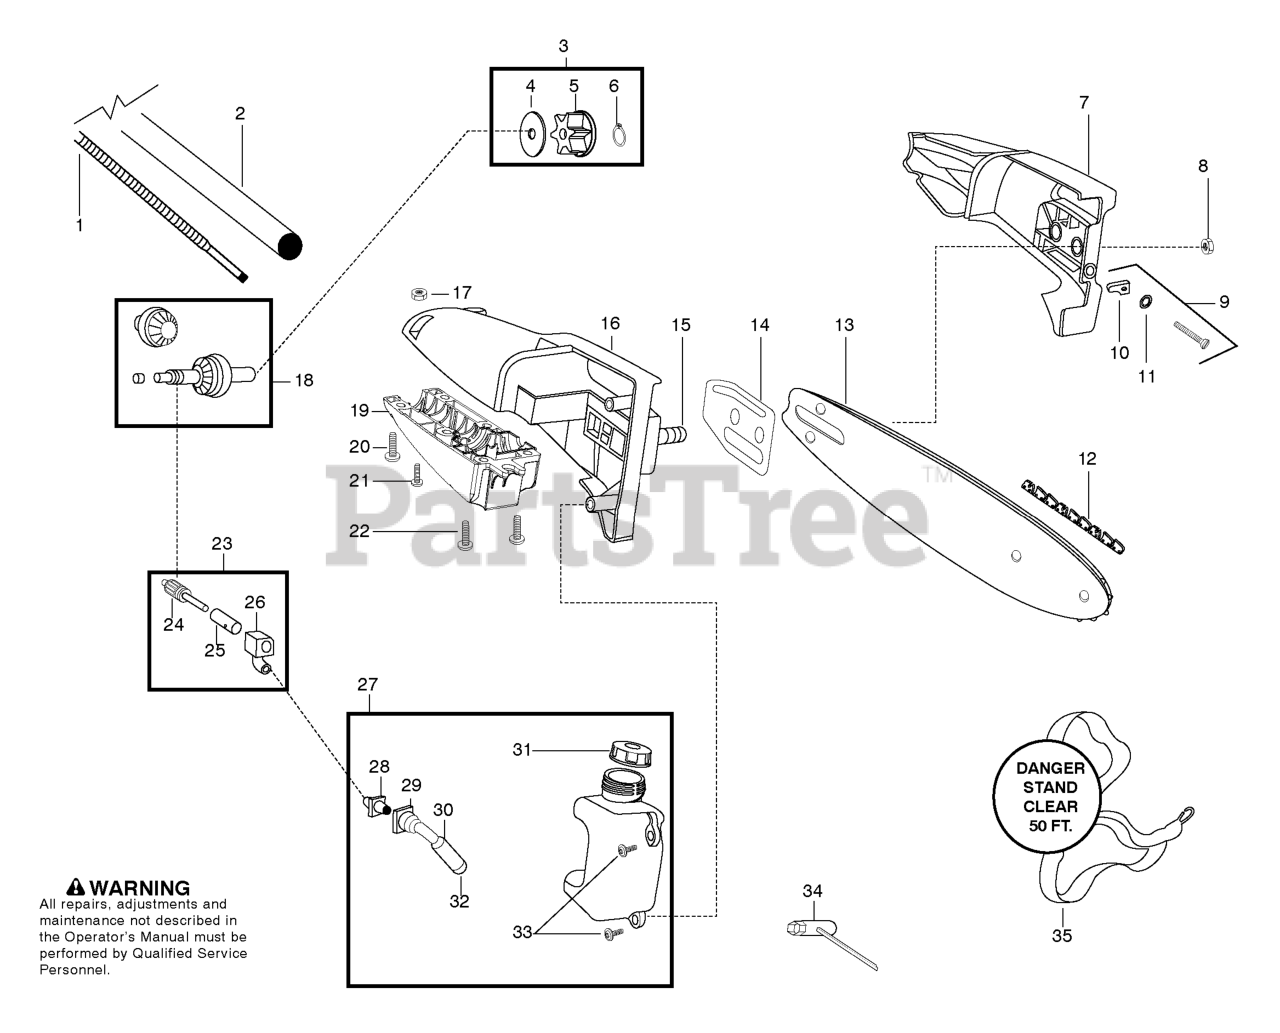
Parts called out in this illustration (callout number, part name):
1	FLEX SHAFT
2	DRIVE SHAFT
3	SPROCKET
6	RING SPROCKET RETAINER
7	BAR CLAMP ASSY - BAR CLAMP (I
9	KIT.RETAINER.BAR ADJUSTMENT
10	ADJUST PIN,BAR 36/41
12	Chain - 8"
14	PAD BAR PLATE
16	HOUSING HOUSING - UPPER (INCL
18	KIT GEAR ASSY
19	HOUSING HOUSING - LOWER
20	SCR 10-24 MS LDK PAN PH
21	SCREW-10-14 X 1/2 PLASTITE
22	SCREW-10-14 X 13/16 (PL
23	OILER
24	ASSY GEAR PLUNGER
27	OIL TANK ASSY-OIL TANK (INCL
28	OIL PUMP FITTING
29	LINE OIL INTAKE
30	FILTER
32	PLUG
34	WRENCH-BAR
35	ASSY,SHOULDER STRAP
